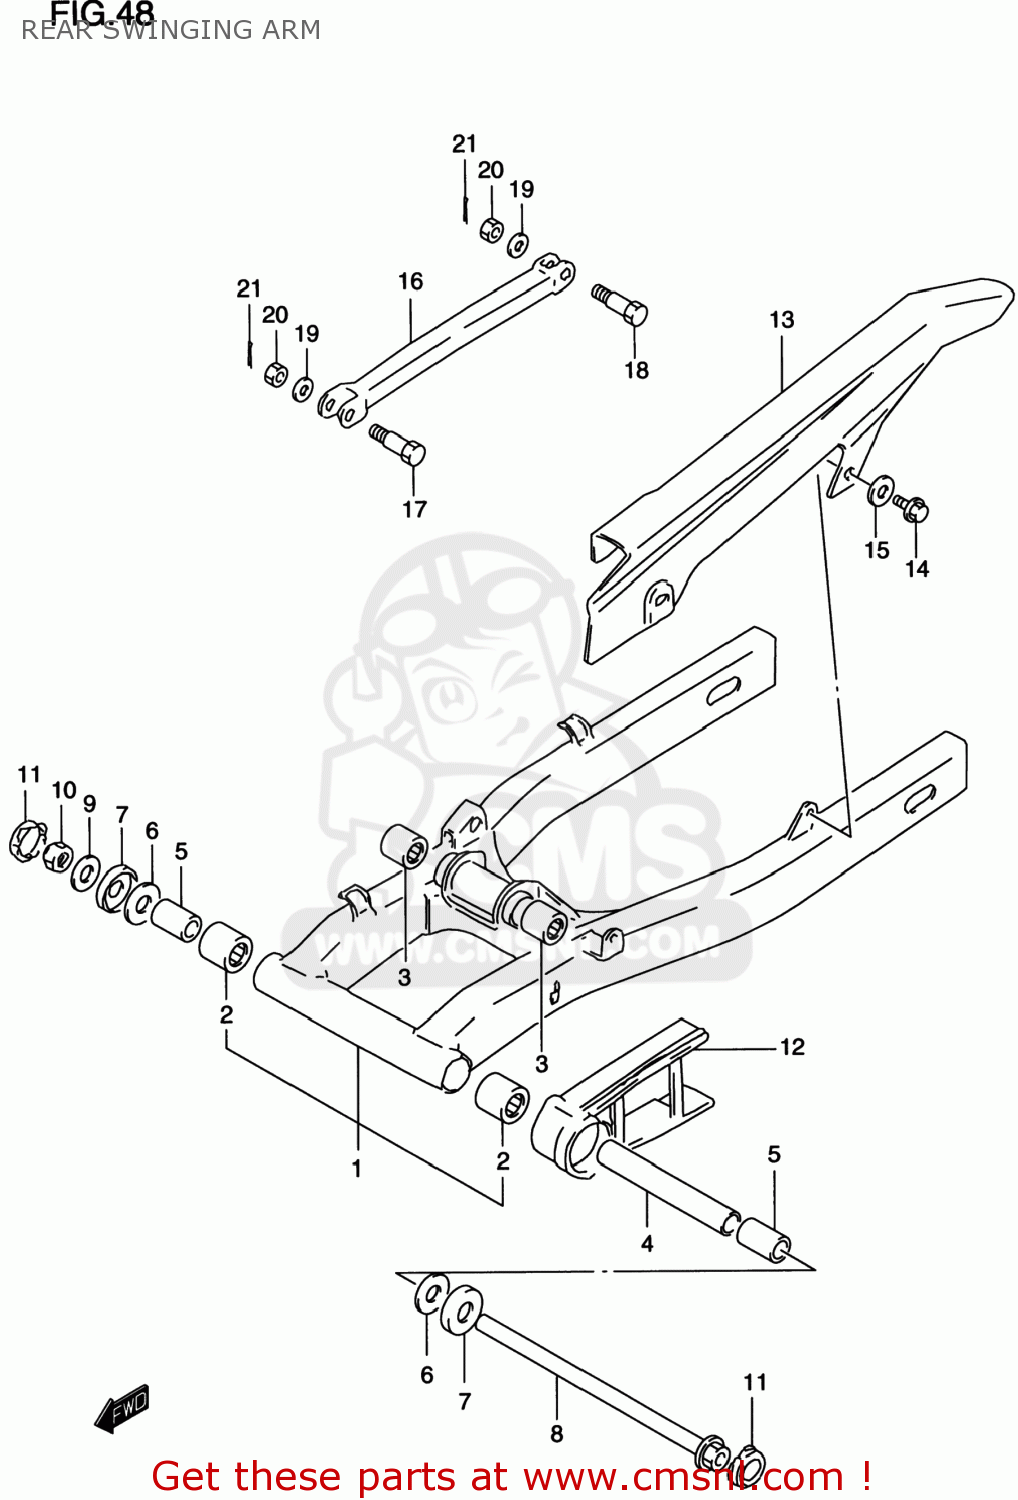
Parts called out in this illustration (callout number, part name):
1	SWINGINGARM ASSY,RR
2	BEARING(22X29X30)
3	BEARING(17X24X25)
4	SPACER,RR SWGARM PIVOT CTR
5	SPACER,RR SWGARM PIVOT
6	WASHER(14.2X34X1)
7	CVR,RR SWGARM DUST SEAL(OD:40)
8	SHAFT,RR SWINGINGARM PIVOT
9	WASHER(14.5X29X2.3)
10	NUT
11	CAP,RR SWINGING ARM PIVOT
12	BUFFER,CHAIN TOUCH DEFENSE
13	CASE,CHAIN
14	SCREW 6X12
15	WASHER
16	TORQUELINK,RR
17	BOLT(10X41)
18	BOLT(10X35)
19	WASHER(10.5X20X3.2)
20	NUT
21	PIN 20X20
